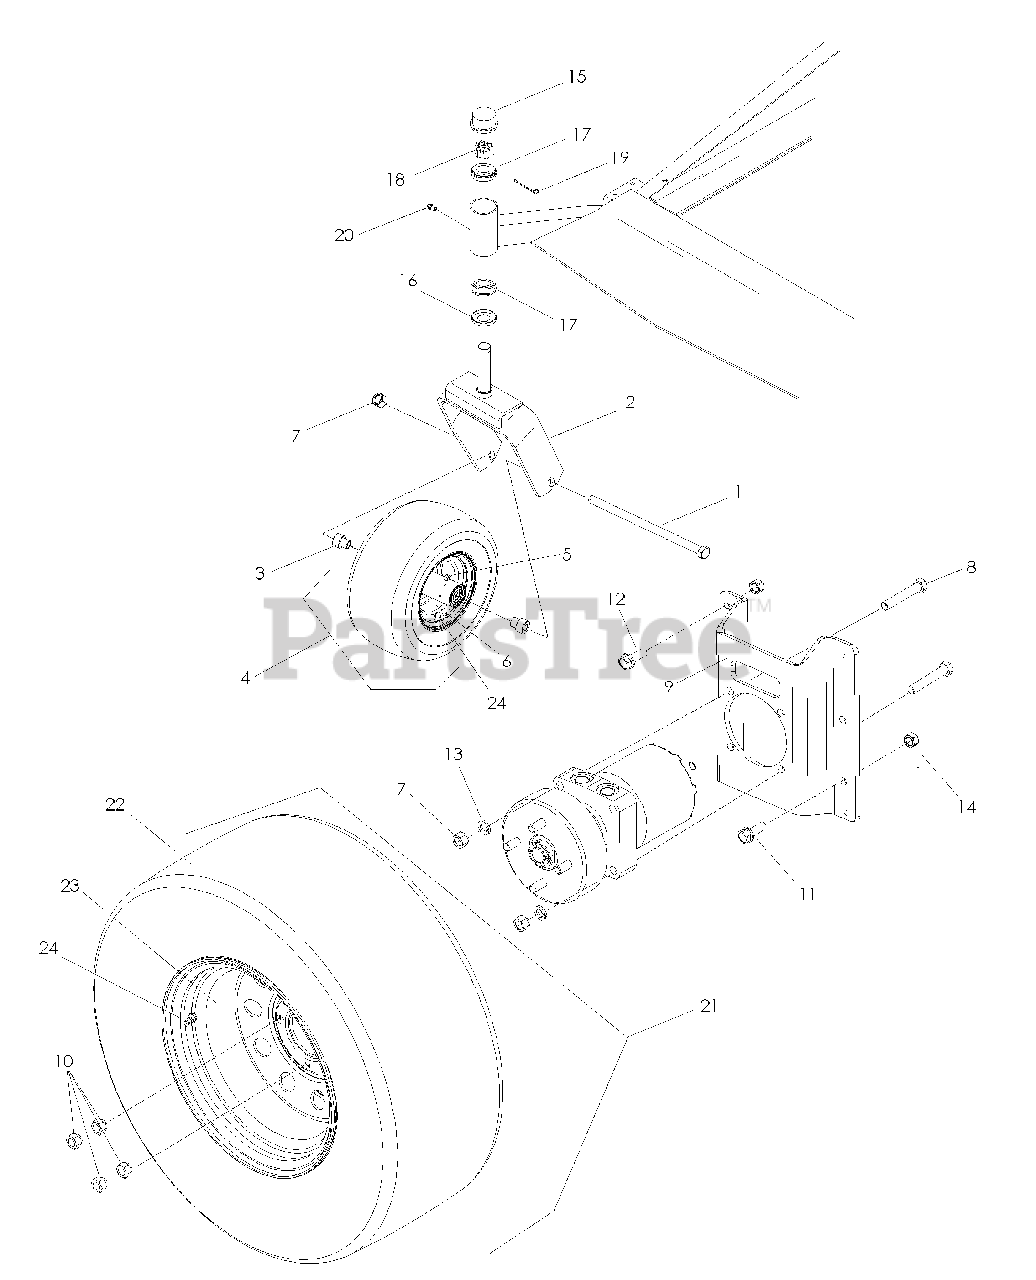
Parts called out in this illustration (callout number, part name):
1	HCS 1/2-13 x9 1/2
2	YOKE, CASTER
3	SPACER, AXLE
4	WHEEL ASSEMBLY, CASTER
5	ZERK
7	NUT 1/2-13 HEX NYLOC
8	HCS 1/2-13 x2 1/2
9	STANDOFF, WHEEL MOTOR
10	LUG NUT 1/2"
11	BOLT 1/2-13 x 1 1/4 WHIZLK
12	HCS 3/8-16 x 1 1/4
13	WASHER 3/8 FLAT STD
14	NUT 3/8-16 HEX NYLOC
15	GREASE CAP
18	SLOTTED JAM NUT 1-14
19	COTTER PIN 1/8 x 2
21	WHEEL ASSEMBLY, REAR
